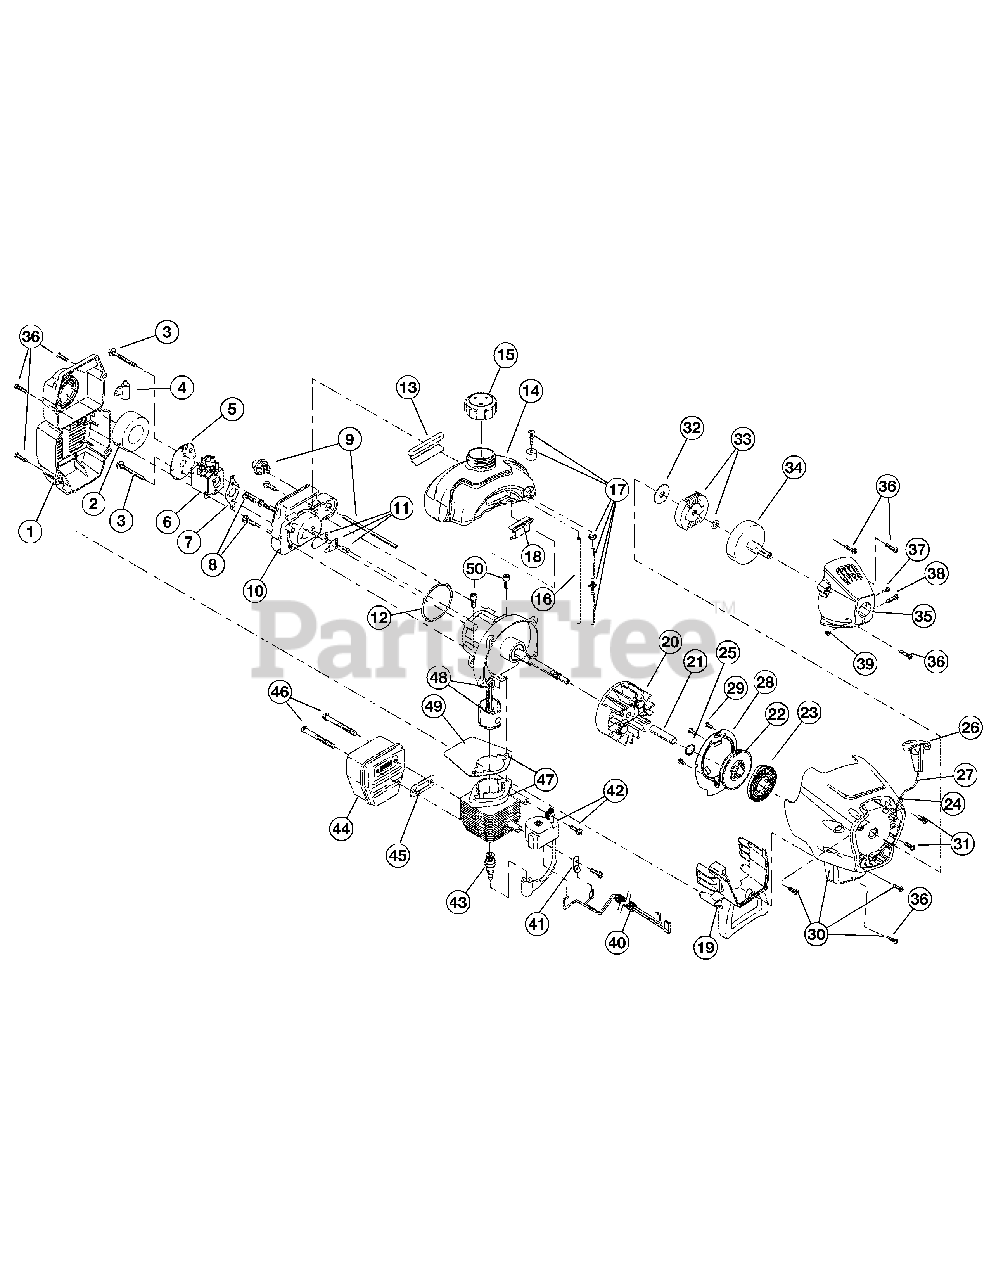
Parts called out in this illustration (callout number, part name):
1	Air Cleaner Assembly (includes 2 & 36)
2	Air Cleaner Filter
3	Carburetor Mounting Screw Assembly
4	Choke Extension
5	Choke Plate
6	Carburetor Assembly (includes 7 & 17)
7	Carburetor Gasket
8	Carb Mount Screw
9	Primer and Hose Assembly
10	Carb Mount Assembly(includes 8, 11 & 12)
11	Reed Assembly
12	Carburetor Mount O-Ring
13	Rear Mounting Pad
14	Fuel Tank Assembly (includes 15-18)
15	Fuel Cap Assembly
16	Fuel Return Line
17	Fuel Line Assembly
18	Front Mounting Pad
19	Shroud Extension & Stand (includes 36)
20	Flywheel Assembly
22	Recoil Pulley Assembly (includes 25)
23	Recoil Spring
24	Rope Guide
25	Palnut
26	Pull Handle
28	Pressure Plate Assembly (includes 29)
29	Plate Screw
30	Starter Housing Assembly
31	Housing Screw
32	Clutch Washer
33	Clutch Rotor Assembly
34	Clutch Drum Assembly
35	Clutch Cover Assembly (includes 36-39)
36	Cover Screw
37	Anti-Rotation Screw
38	Clamping Screw
39	Clamping Nut
40	Wire Leads and Sleeve
41	Ground Tab
42	Module Assembly (includes 41)
43	Spark Plug
44	Muffler Assembly (includes 45 & 46)
45	Exhaust Gasket
46	Muffler Mounting Bolts
47	Cylinder Assembly (includes 49 & 50)
48	Piston and Rod Assembly
49	Cylinder Gasket
50	Cylinder Bolt
